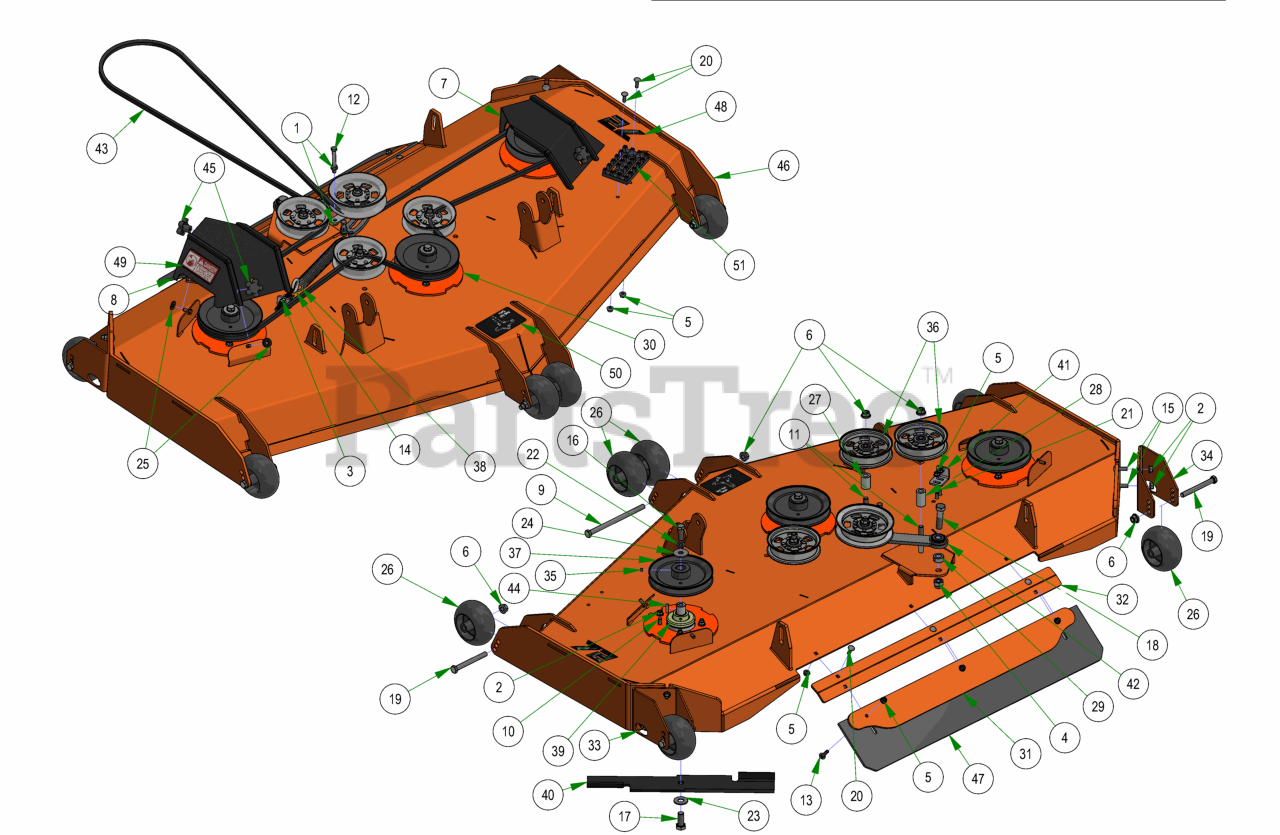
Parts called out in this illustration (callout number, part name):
1	3/8-16 HEX SERRATED FLANGE NUT HARD/ZINC
2	3/8-16 NYLON INSERT FLANGE LOCKNUT (GR.F) ZINC
3	3/8-16 HEX NUT ZINC
4	5/8-11 NYLON INSERT LOCKNUT ZINC
5	5/16-18 NYLON INSERT FLANGE LOCKNUT ZINC
6	1/2-13 NYLON INSERT FLANGE LOCKNUT ZINC
7	2019 72" Left Outlaw Gen2 Pulley Cover
8	2019 72" Right Outlaw Gen2 Pulley Cover
9	1/2-13 X 8 HEX CAP SCREW GR 5 ZINC
10	3/8-16 X 1-3/4 HEX C/S (GR.5) ZC
11	1/2-13 X 3-1/2 HEX FLANGE BOLT (GR.8) ZINC
12	3/8-16 X 3 HEX CAP SCREW (GR.5) ZINC
13	5/16-18 X 1-1/4 CARRIAGE BOLT ZINC
14	4" 3/8-16 Eye Bolt
15	3/8-16 X 1-1/4 CARRIAGE BOLT ZINC
16	1/2-20 X 1-1/2 HEX CAP SCREW (GR.5) ZINC
17	5/8-18 X 1-1/2 HEX CAP SCREW (GR.8) ZINC YELLOW
18	5/8-11 X 2-1/2 HEX CAP SCREW (GR.5) ZINC
19	1/2-13 X 4-1/2 HEX CAP SCREW (GR.5) ZINC
20	5/16-18 X 1 CARRIAGE BOLT (GR.8) ZINC
21	5/16-18 X 7/8 CARRIAGE BOLT ZINC
22	1/2 SPLIT LOCKWASHER (GR.8) ZINC/YELLOW
23	5/8 USS FLAT WASHER (1-3/4" OD) GR.8 ZINC YELLOW
24	1/2 BELLEVILLE WASHER (1-5/8 OD X .140 THK) ZINC
25	.360 ID X .983 OD X .120 THICK FLAT WASHER NYLON BLACK
26	2019 Deck Wheel
27	.502 ID X .750 OD X 1.500 Long Spacer
28	1 3/4" Pulley Spacer
29	5/8 SOLID SHAFT COLLAR (W/1 SET SCREW) ZINC
30	Deck Spindle Support Plate
31	61 Bolt in Baffle Deck v2 Stripping Plate
32	Rubber Mount Plate - Rear Discharge
33	LH Rear Deck Wheel Bracket - Rear Discharge
34	RH Rear Deck Wheel Bracket - Rear Discharge
35	5/16-24 X 1/4 SOCKET SET SCREW (CUP PT) PLAIN
36	5-3/4 Idler Pulley
37	7" Deck Pulley
38	2019 Outlaw Gen2 Deck Spring
39	OUTLAW SPINDLE ASSEMBLY
40	72" High Lift Fusion Blade
41	2019 Deck Eye Bolt Tab
42	2019 Rebel Rogue Deck Idler
43	B202 Belt for 72" Outlaw
44	1/4 X 1 SQ MACHINERY KEY 1018 STL PLN
45	5/16" Knob
46	72 Rear Discharge Deck
47	R Series Rubber For Deck
48	72" Deck Decal
49	Danger Decal-Spindle/Discharge
50	2019 Rebel & Rogue Deck Belt Route Decal
51	Deck Step Assembly
